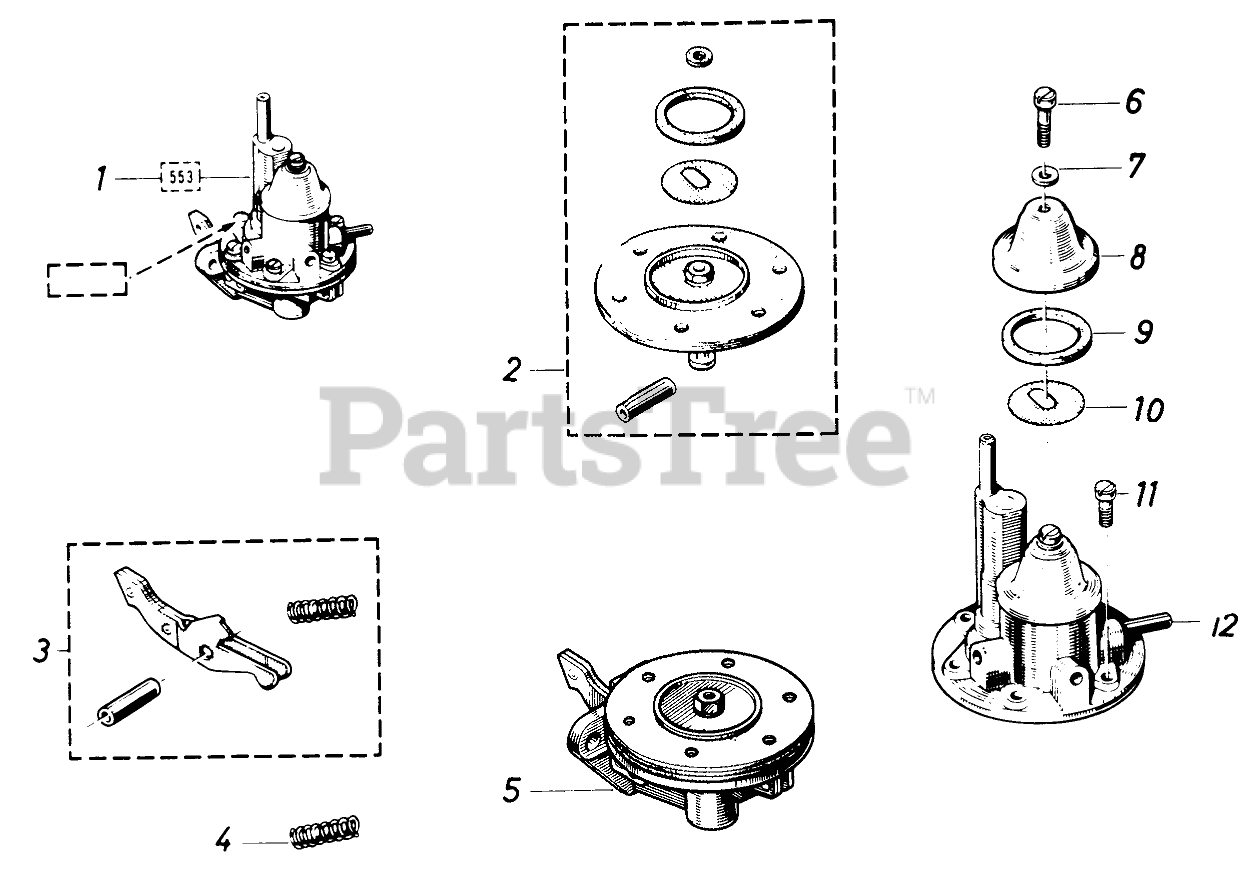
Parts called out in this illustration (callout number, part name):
1	Fuel Pump Cpl.
2	Spare Parts Set
3	Spare Parts Set
4	Spring
5	Housing, Lower Assy.
6	Screw
7	Gasket
8	Cover
9	Gasket
10	Filter
11	Screw
12	Housing Upper Part Assy.
